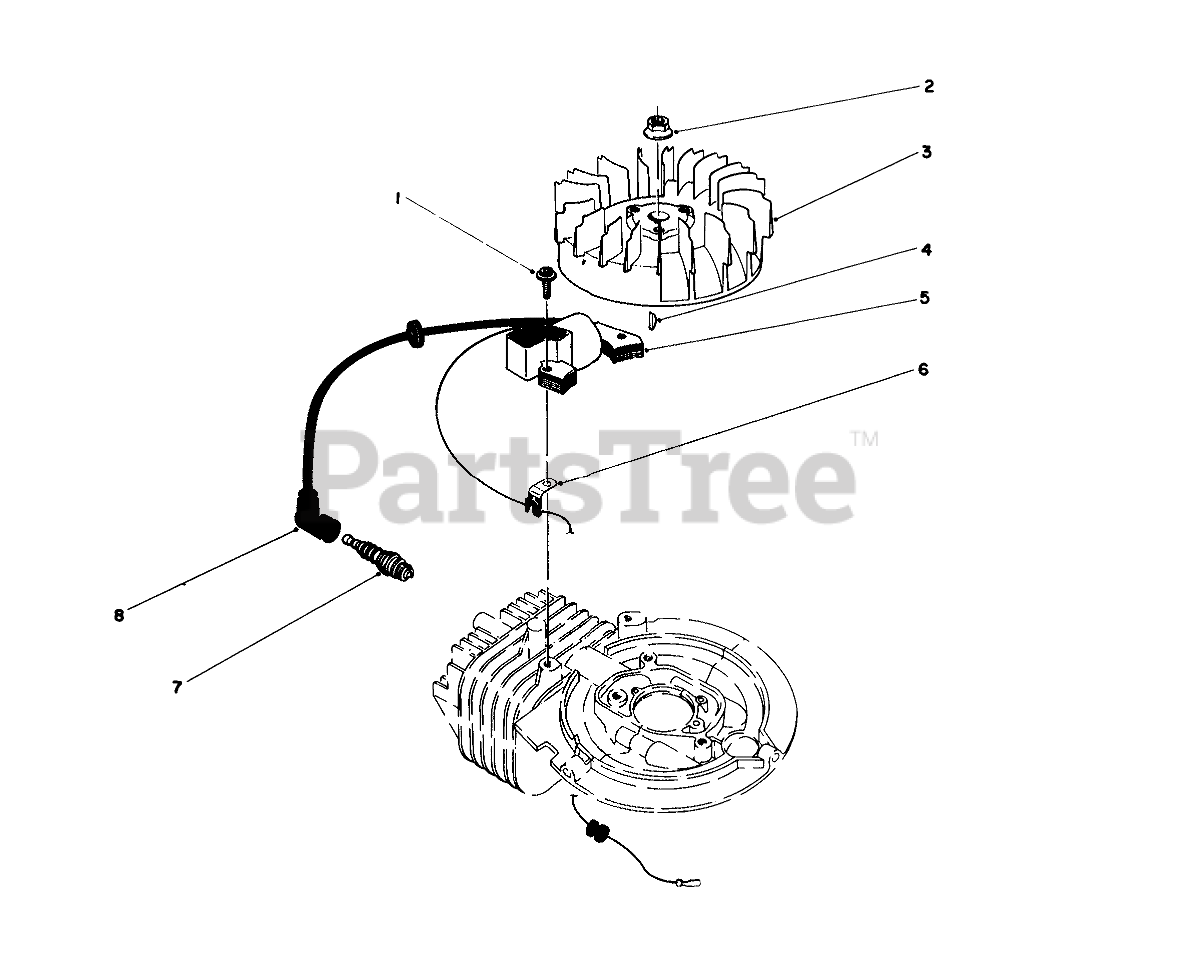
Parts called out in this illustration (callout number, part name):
1	Allenhead
3	FLYWHEEL
4	Key-Flywheel
5	Coil/Ignition Assembly
6	CLAMP
7	Spark Plug
8	CAP-SPARKPLUG
